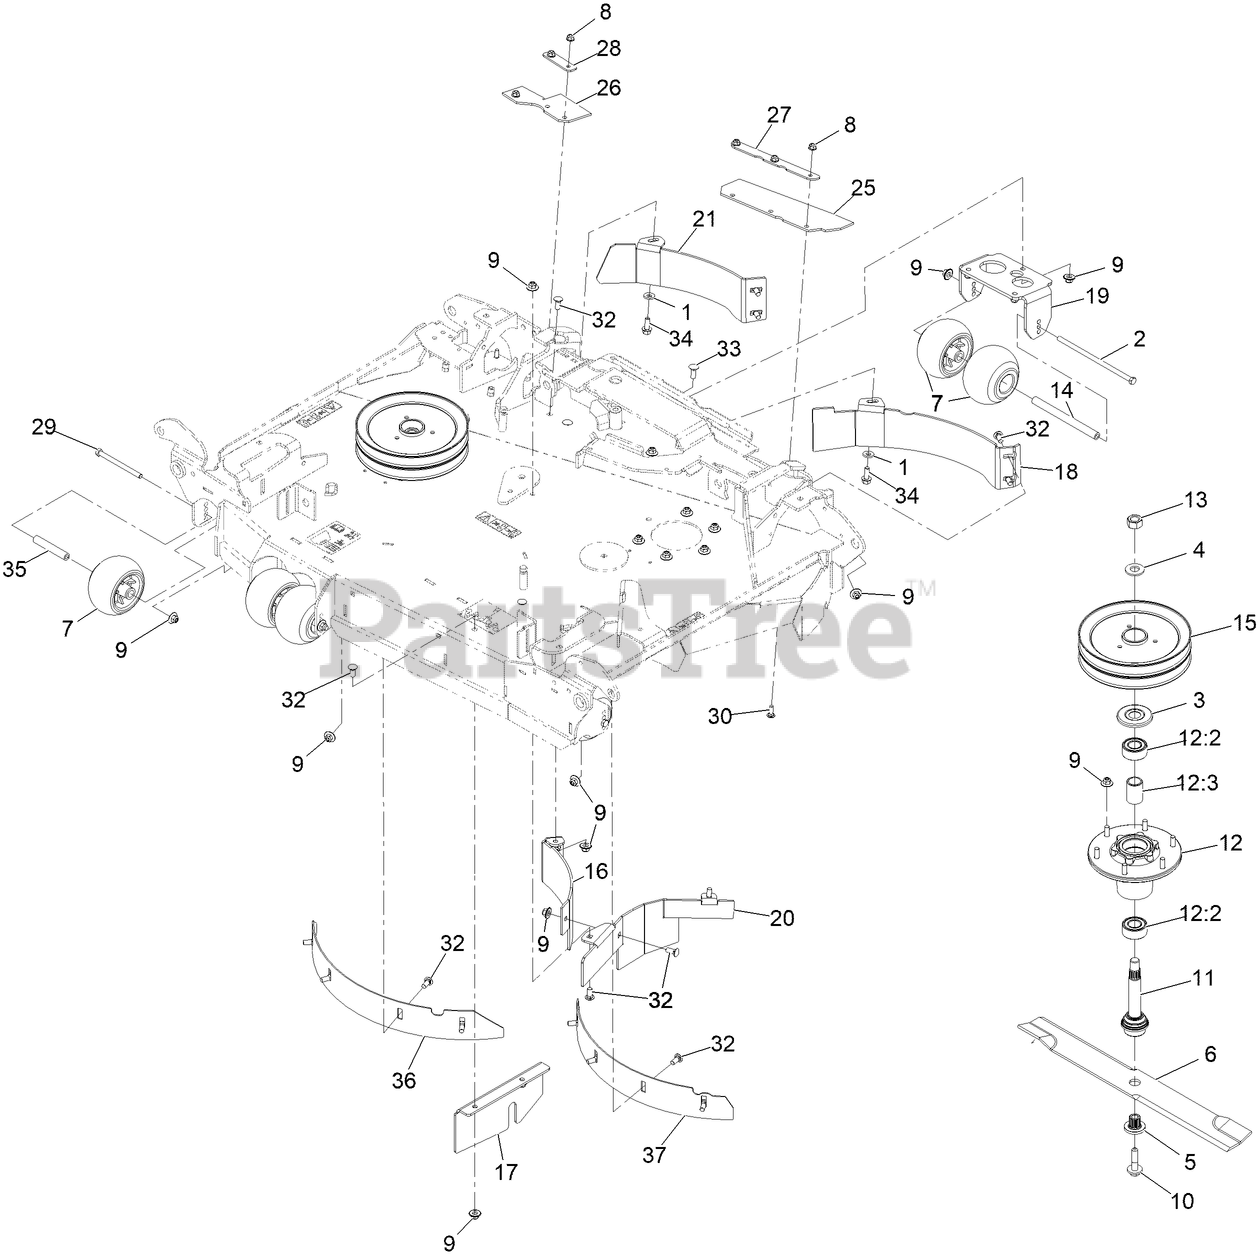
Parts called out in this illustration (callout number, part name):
1	WASHER-BELLEVILLE
2	SCREW-HH
3	GUARD-BEARING, TOP
5	BUSHING,SPLINED
7	ROLLER-SCALP, ANTI
8	NUT-HF, NI
9	Nut-Nyloc 3/8-16 Flg
10	SCREW,SEMS 1/2-20 X 2.19
11	ASM-SPINDLE AND SEAL
12	ASM-CUTTER HSG
12:2	BEARING-3205 TRASHGUARD
12:3	SPACER-BEARING
13	NUT-HEX
14	SPACER-WHEEL
15	SHEAVE-DOUBLE 96RD
16	BAFFLE-CENTER, REAR (RH)
17	PLATE-BLOCK, FRONT
18	BAFFLE-BLOCK, LH CTR
19	BRACKET-ANTISCALP, REAR
20	BAFFLE-CENTER
21	BAFFLE-BLOCK, RH CTR
25	Flap-Discharge
26	Flap-Discharge
27	Support-Flap
28	Support-Flap, RH
29	SCREW-HH
30	SCREW-CARR
32	BOLT-CARR
33	BOLT-CARR
34	SCREW-HHF
35	SPACER-WHEEL SHORT
36	BAFFLE-DEPTH, LH
37	BAFFLE-DEPTH, RH
